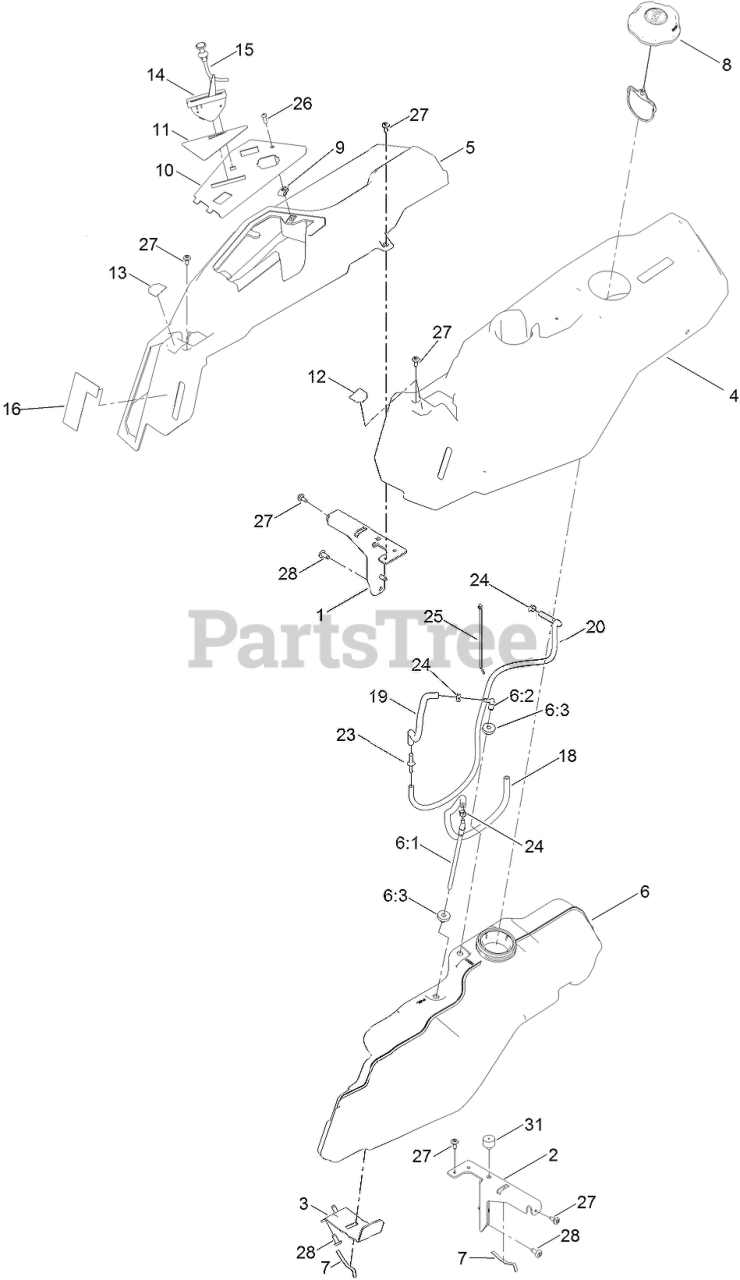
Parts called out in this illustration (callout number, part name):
1	SUPPORT-POD, RH
2	SUPPORT-POD, LH
3	SUPPORT-TANK, FUEL
4	POD-LH
5	POD-RH
6	FUEL TANK ASM
6:1	CONNECTOR-ELBOW, 90 DEG
6:2	FITTING-PLASTIC
6:3	BUSHING
7	SPRING
8	CAP-FUEL, RATCHETING
10	PANEL-CONTROL
11	DECAL-PANEL, CONTROL
12	DECAL-CONTROL LEVER, LH
13	DECAL-CONTROL LEVER, RH
14	CABLE-THROTTLE
15	CABLE-CHOKE
16	DECAL-SMART SPEED
18	HOSE-FUEL
19	HOSE-FUEL
20	HOSE-FUEL
23	ADAPTOR-ORIFICE
24	CLAMP-HOSE
25	TIE-CABLE
26	SCREW-PRH
27	SCREW-SHOULDER
31	BUMPER-GROMMET
